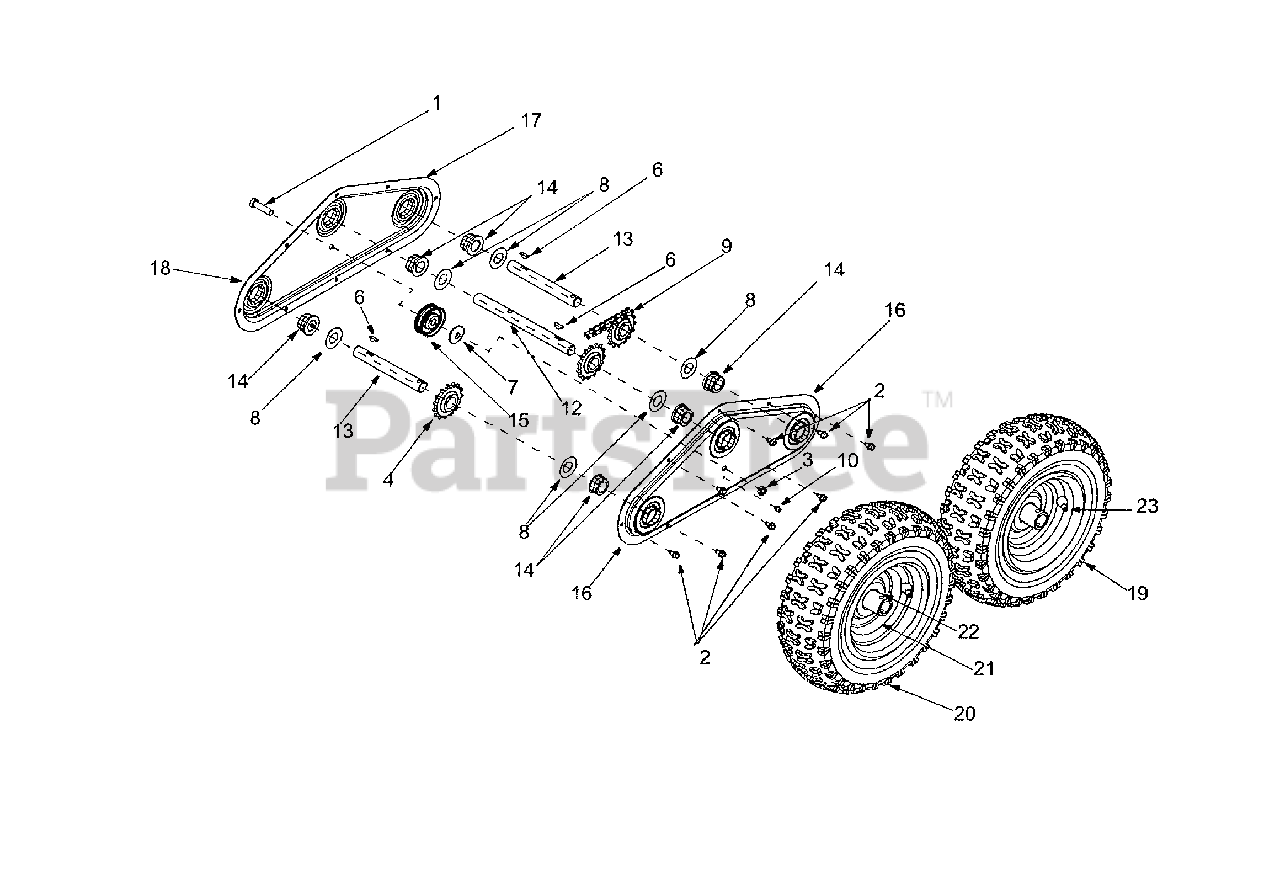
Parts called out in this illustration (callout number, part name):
1	Special Hex Screw: 3/8-24 x .5"
2	TT Screw: 1/4-20 x 0.5"
6	Key
7	Flat Washer
8	Flat Washer
9	Lubricant: 6in 1
10	Lube Fitting
12	Drive Axle
13	Wheel Axle
14	Hex Flange Bearing
15	Flat Idler
18	Chain Case Assembly RH
23	Air Valve
